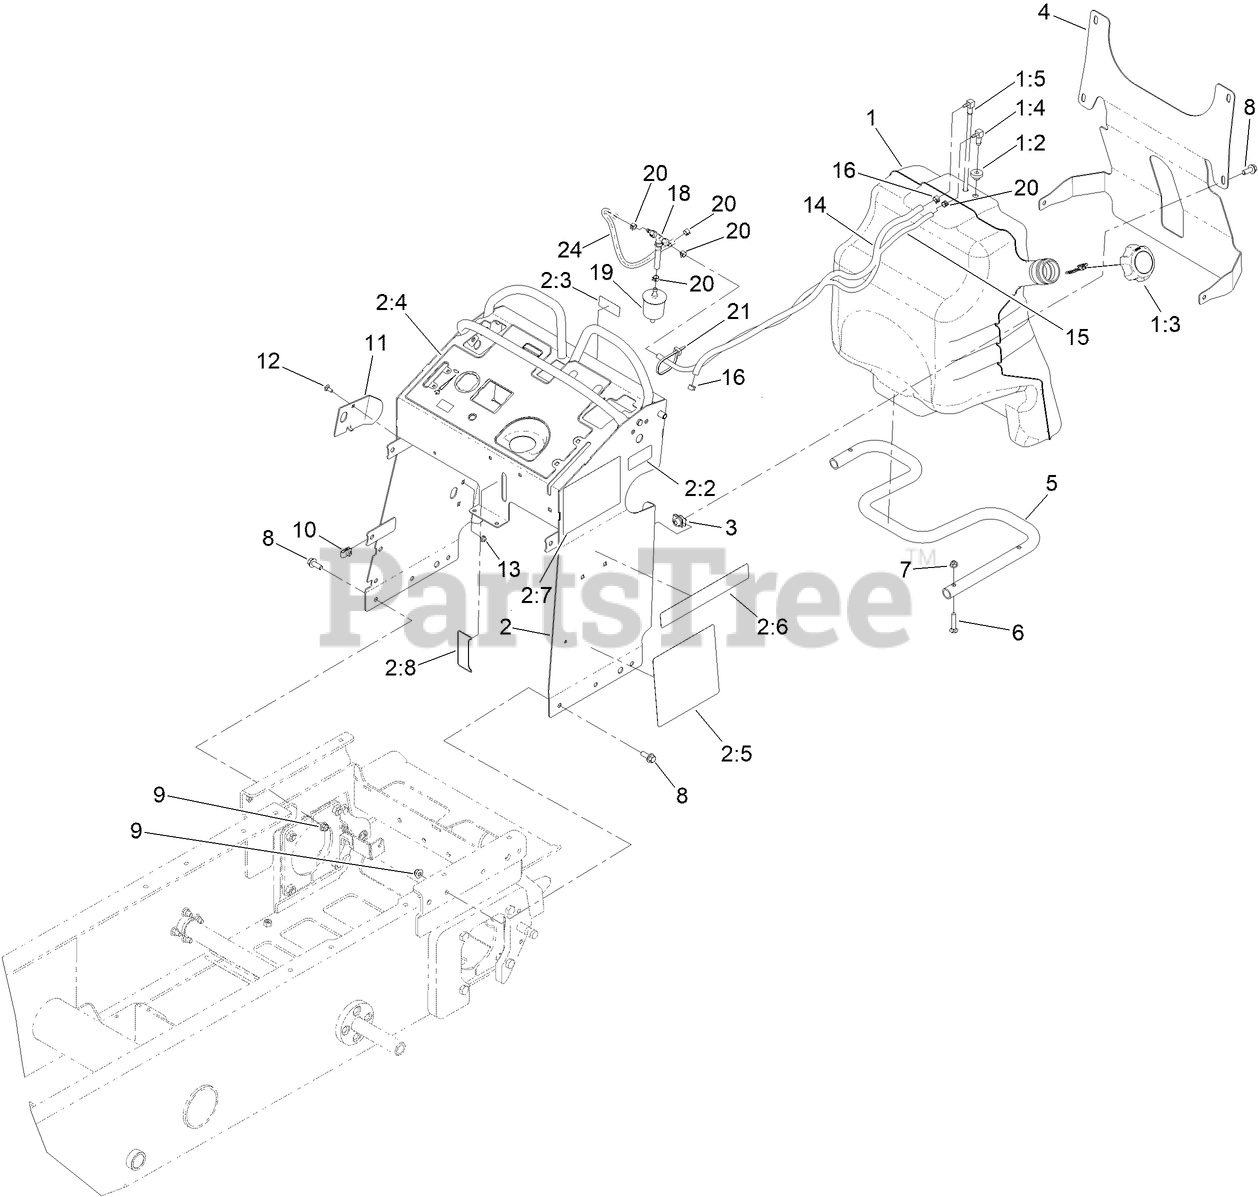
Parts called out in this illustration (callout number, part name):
1	FUEL TANK ASM
1:2	BUSHING
1:3	CAP-FUEL
1:4	FITTING-ELBOW, 90 DEG
1:5	ASM, TUBE-FUEL
2	TOWER ASM
2:2	DECAL-FILL, FUEL
2:3	DECAL-FUSE
2:4	DECAL-CONTROL PANEL
2:5	DECAL-SERVICE
2:6	DECAL, MBTX-2500
2:7	DECAL-SRVSW5X7
2:8	DECAL-LEVEL, OIL
3	NUT-TINNERMAN
4	BRACKET-CROSS
5	TUBE-FUEL TANK MOUNT
6	BOLT-CAR
7	NUT-HF, NI
8	SCREW-HHF
9	NUT-HF, NI
10	NUT-CLIP, U
11	PLATE-STRIKER
12	SCREW-CARR
13	NUT-HF
14	HOSE-FUEL
15	HOSE-FUEL
16	CLAMP-HOSE
18	TEE AND CHECK
19	FILTER-FUEL
20	CLAMP-HOSE
21	TIE-CABLE
24	HOSE-VENT
